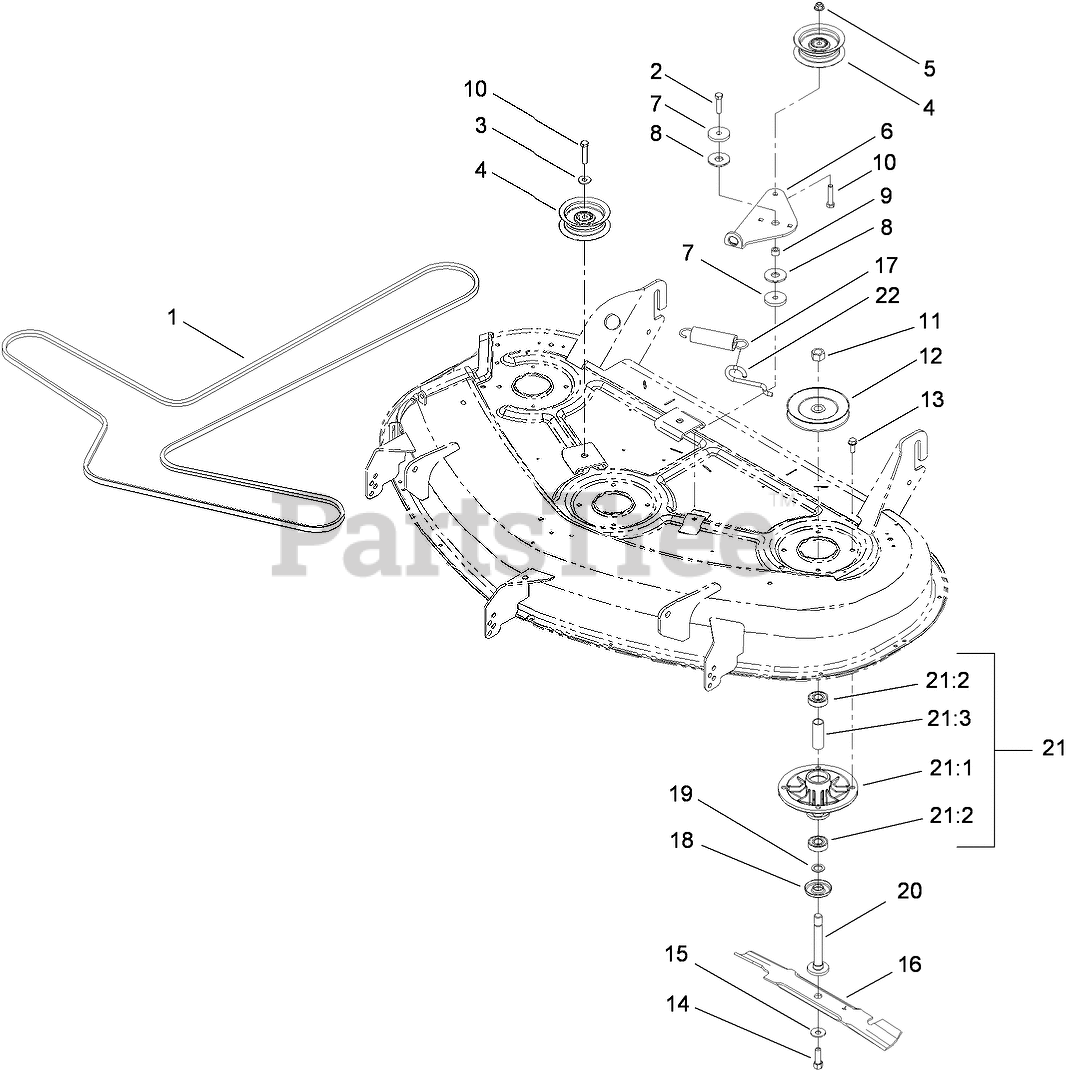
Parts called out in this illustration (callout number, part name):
1	V-BELT
2	SCREW-HH
3	WASHER-HARDENED
4	PULLEY-IDLER, FLAT
5	NUT-HF, NI
6	ARM-IDLER
7	WASHER-PLAIN
8	WASHER-FRICTION, COMPOSITE
9	SPACER
10	SCREW-HH
11	NUT-HEX
12	PULLEY
13	SCREW-TAPTITE
14	SCREW-HH
15	WASHER-BELLEVILLE
16	BLADE-HI-FLO, 17.50 INCH
17	SPRING-EXTENSION
18	SHIELD-BEARING
19	SPACER
20	SHAFT-SPINDLE
21	SPINDLE ASM
21:1	HOUSING-SPINDLE
21:2	BEARING-BALL
21:3	SPACER
22	HOOK-RETURN, SPRING
